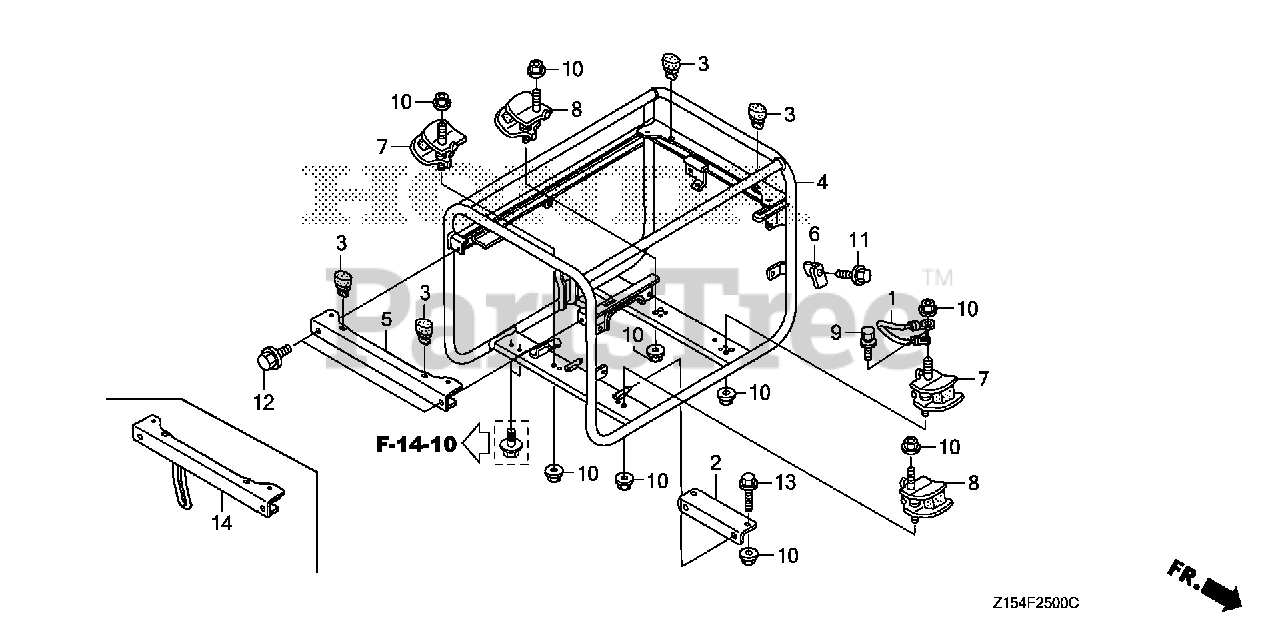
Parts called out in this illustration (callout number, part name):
1	CABLE, SUB-GROUND
2	BRACKET, STOPPER
3	RUBBER, FUEL TANK MOUNTING
4	FRAME *NH1* (CX) (BLACK)
5	FRAME, SIDE *NH1* (CX) (BLACK)
6	PLATE, GUARD
7	RUBBER, FR. (LOWER)
8	RUBBER, RR. (LOWER)
9	BOLT, GROUND (6X16) (WASHER 12.5MM) (ZN)
10	NUT, FLANGE (8MM)
11	BOLT, FLANGE (6X12)
12	BOLT, FLANGE (8X16)
13	BOLT, FLANGE (8X35)
14	FRAME, SIDE *NH1* (CX) (BLACK)
